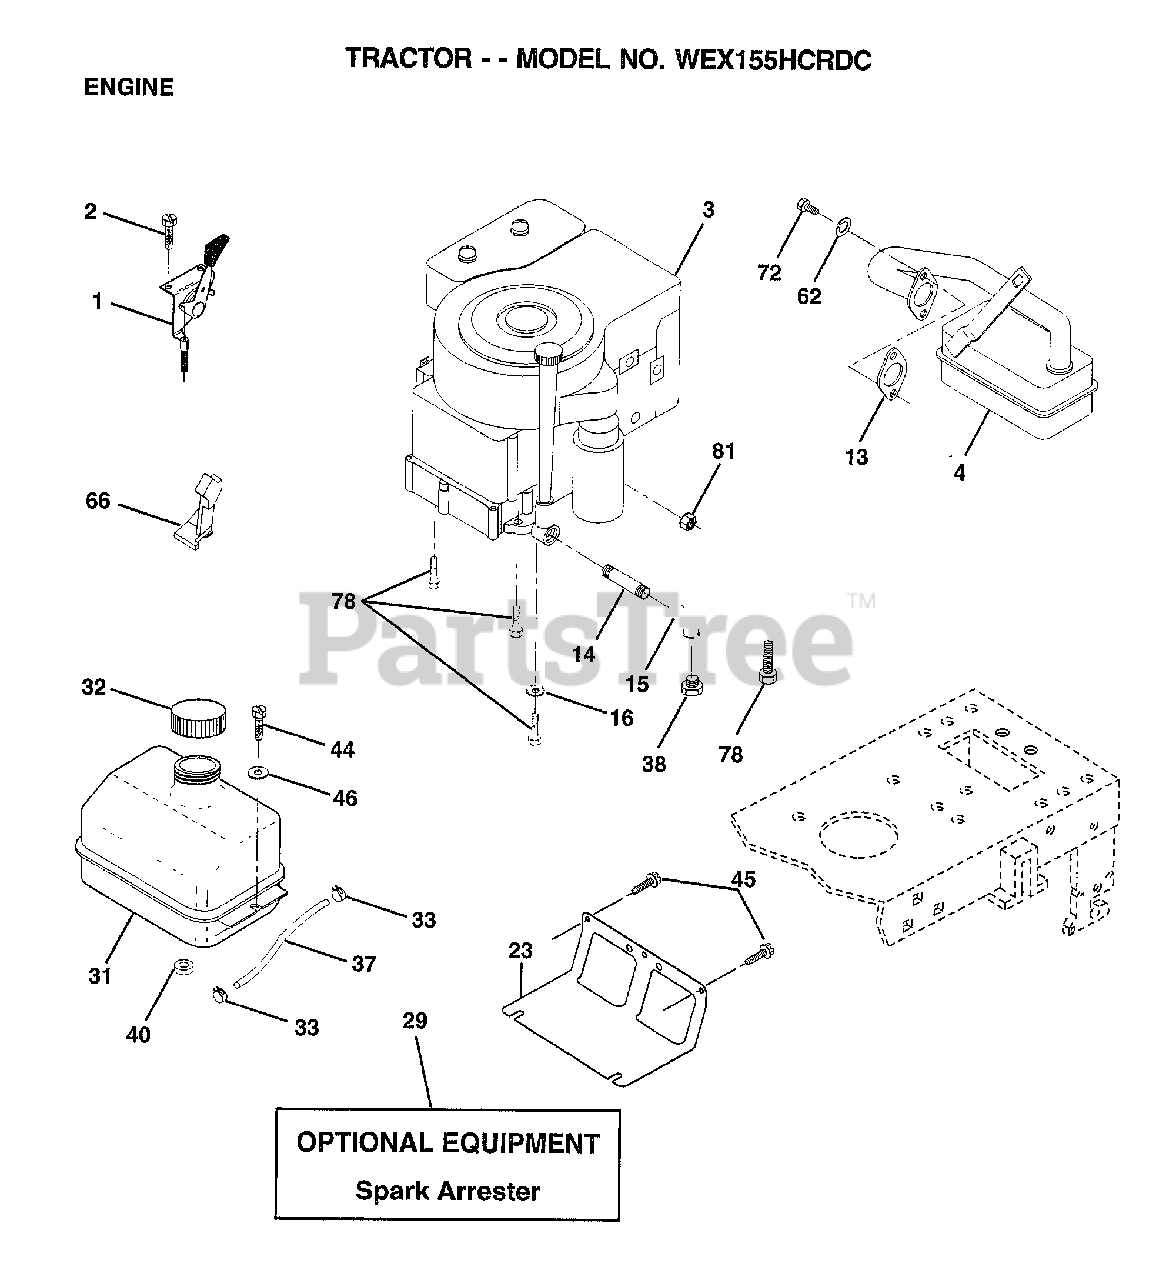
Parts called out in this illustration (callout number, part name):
1	CONTROL.THTL.23.5
2	SCREW LT
4	MUFFLER
14	PIPE NIPPLE LT
15	ELBOW
16	LOCKWASHER
23	SHIELD BROWNING
31	TANK.FUEL.LT.
32	CAP ASM FUEL
33	HOSE CLAMP
37	LINE FUEL
44	SCREW HEX CRT
45	SCREW
46	WASHER
62	LOCKWASHER
66	"STOP,DASH THROTT"
72	SCREW
78	SCREW
81	NUT
